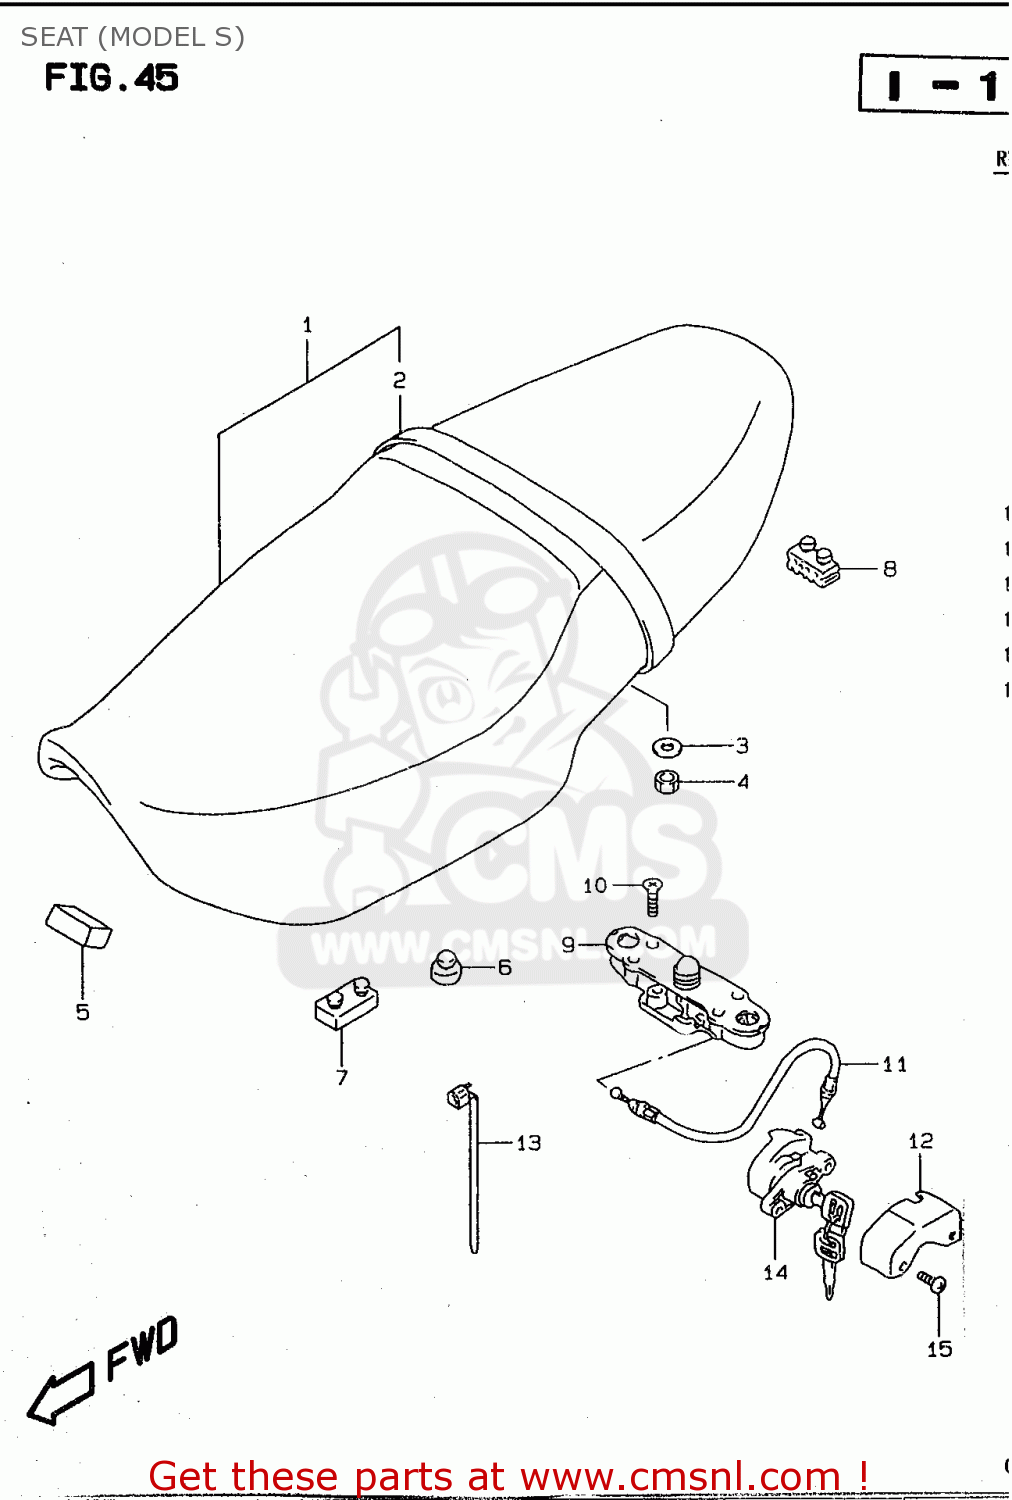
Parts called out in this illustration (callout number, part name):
1	SEAT ASSEMBLY
2	BAND ASSEMBLY,SEAT
3	WASHER
4	NUT
5	CUSHION,TOOL(40X30X15)
6	CUSHION
7	CUSHION
8	CUSHION,SEAT(40X20X15)
9	LOCK ASSY,SEAT STRIKER
10	SCREW 6X30
11	CABLE,SEAT LOCK
12	GUARD,SEAT LOCK
13	CLAMP L:165
14	LOCK SET,SEAT
15	SCREW(6X14)
